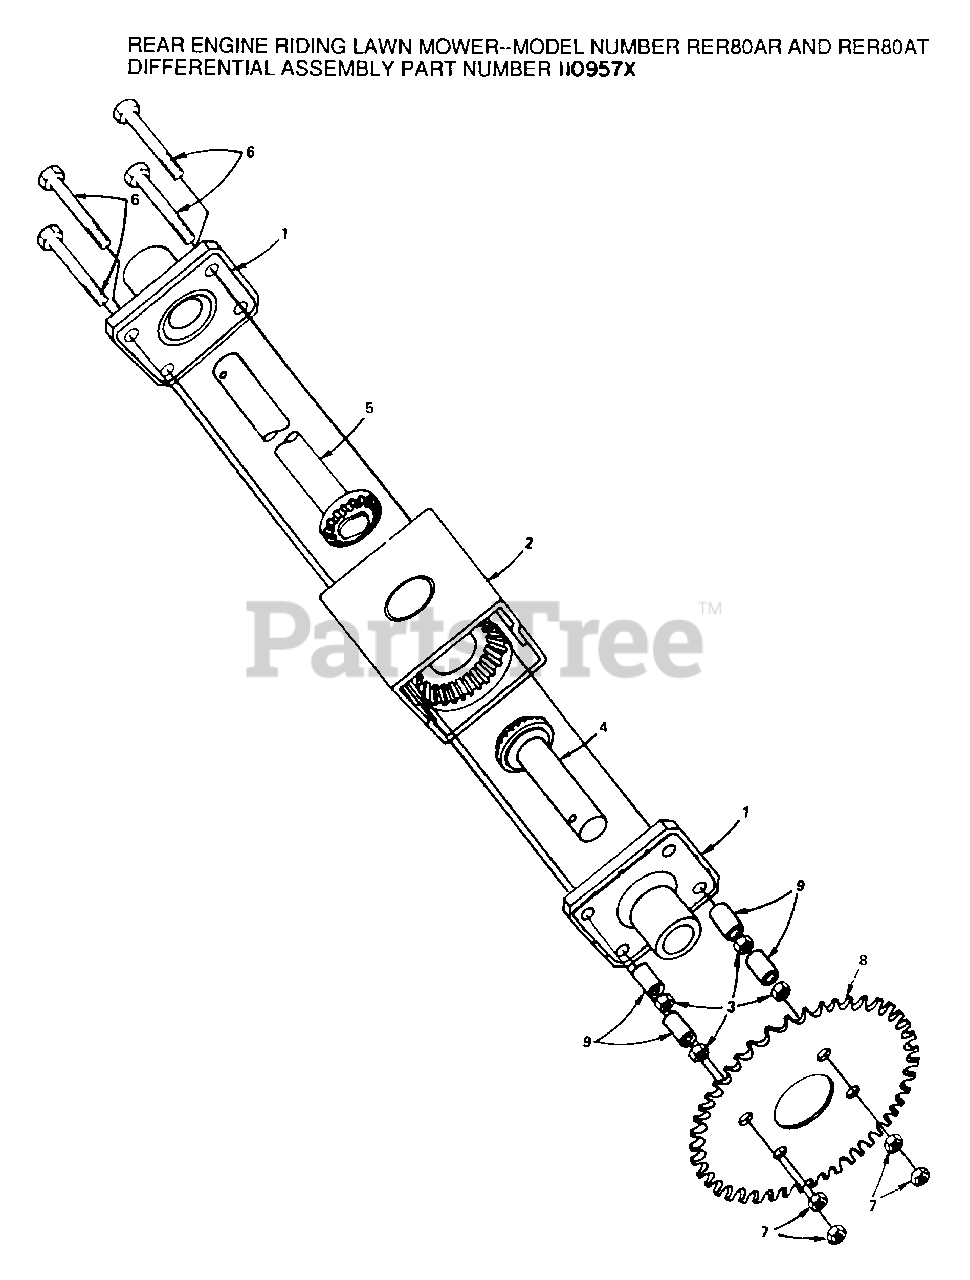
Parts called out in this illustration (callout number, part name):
1	CAPBEAR ASSY
2	TRANSFER GEAR CASE ASSY
3	NUT.HEX.5/16-18
5	GEAR SHAFT L RE
6	BOLT
9	SPACKER - SPROCKET
